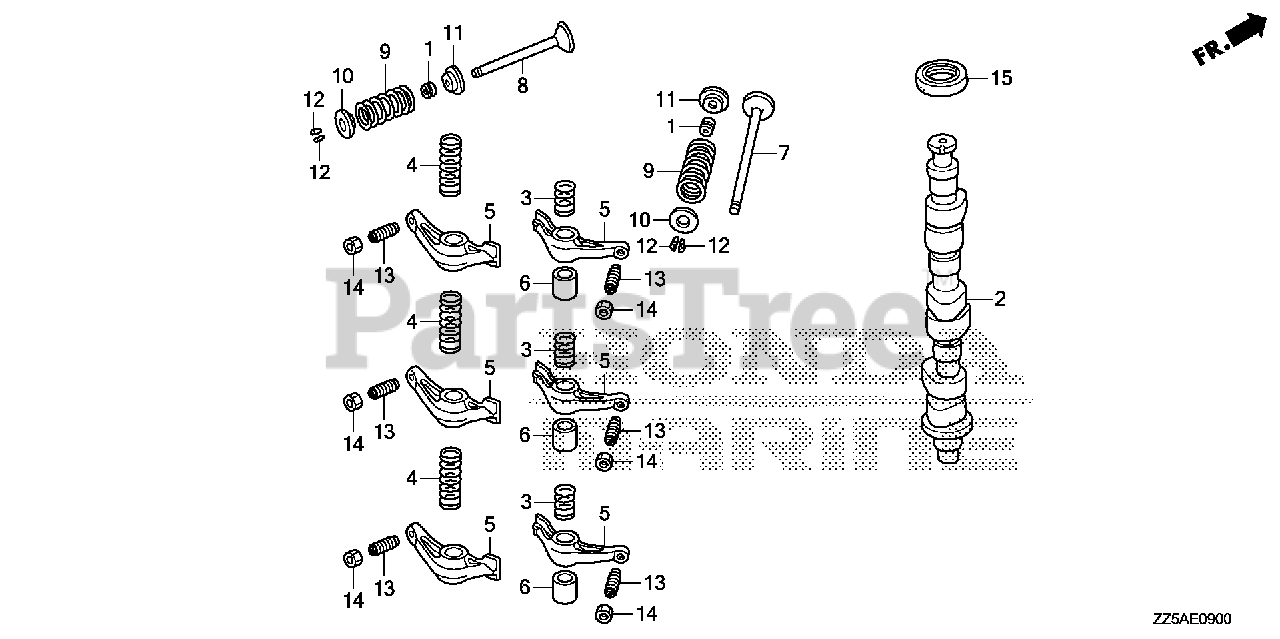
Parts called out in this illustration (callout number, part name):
1	SEAL, VALVE STEM
3	SPRING, ROCKER ARM A
4	SPRING, ROCKER ARM B
5	ARM, IN. ROCKER
6	COLLAR, ROCKER
7	VALVE, IN.
8	VALVE, EX.
9	SPRING, VALVE
10	RETAINER, VALVE SPRING
11	SEAT, VALVE SPRING
12	COTTER, VALVE
13	SCREW, TAPPET ADJUSTING
14	NUT, TAPPET ADJUSTING
15	OIL SEAL (30X42X8)
